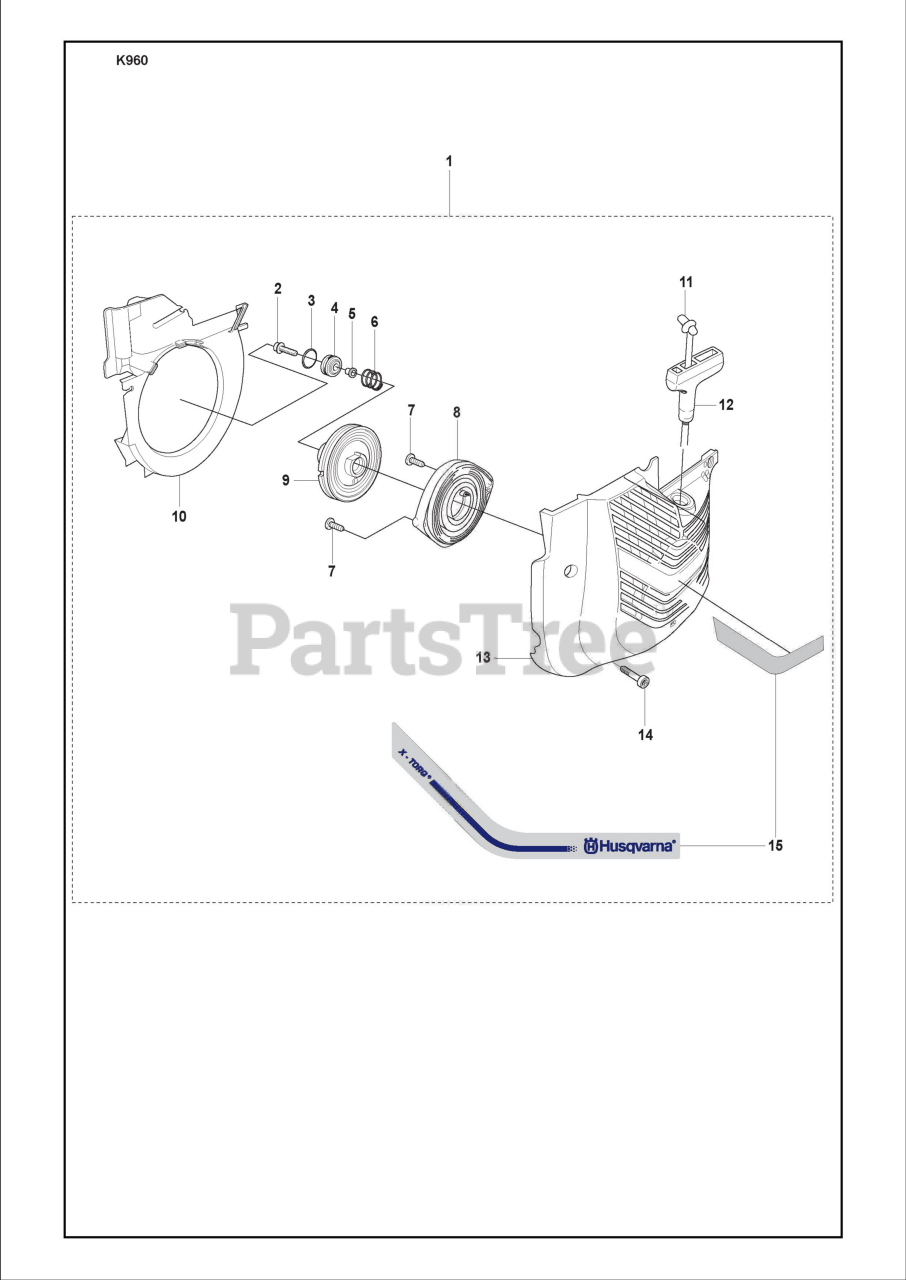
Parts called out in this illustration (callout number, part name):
1	Starter
2	Screw
4	Grommet
5	Spacing Sleeve
6	Compression Spring
8	Recoil Spring
9	Starter Pulley
10	Cooling Air Conductor
11	Starter Cord
12	Starter Handle
13	Starter Cover
